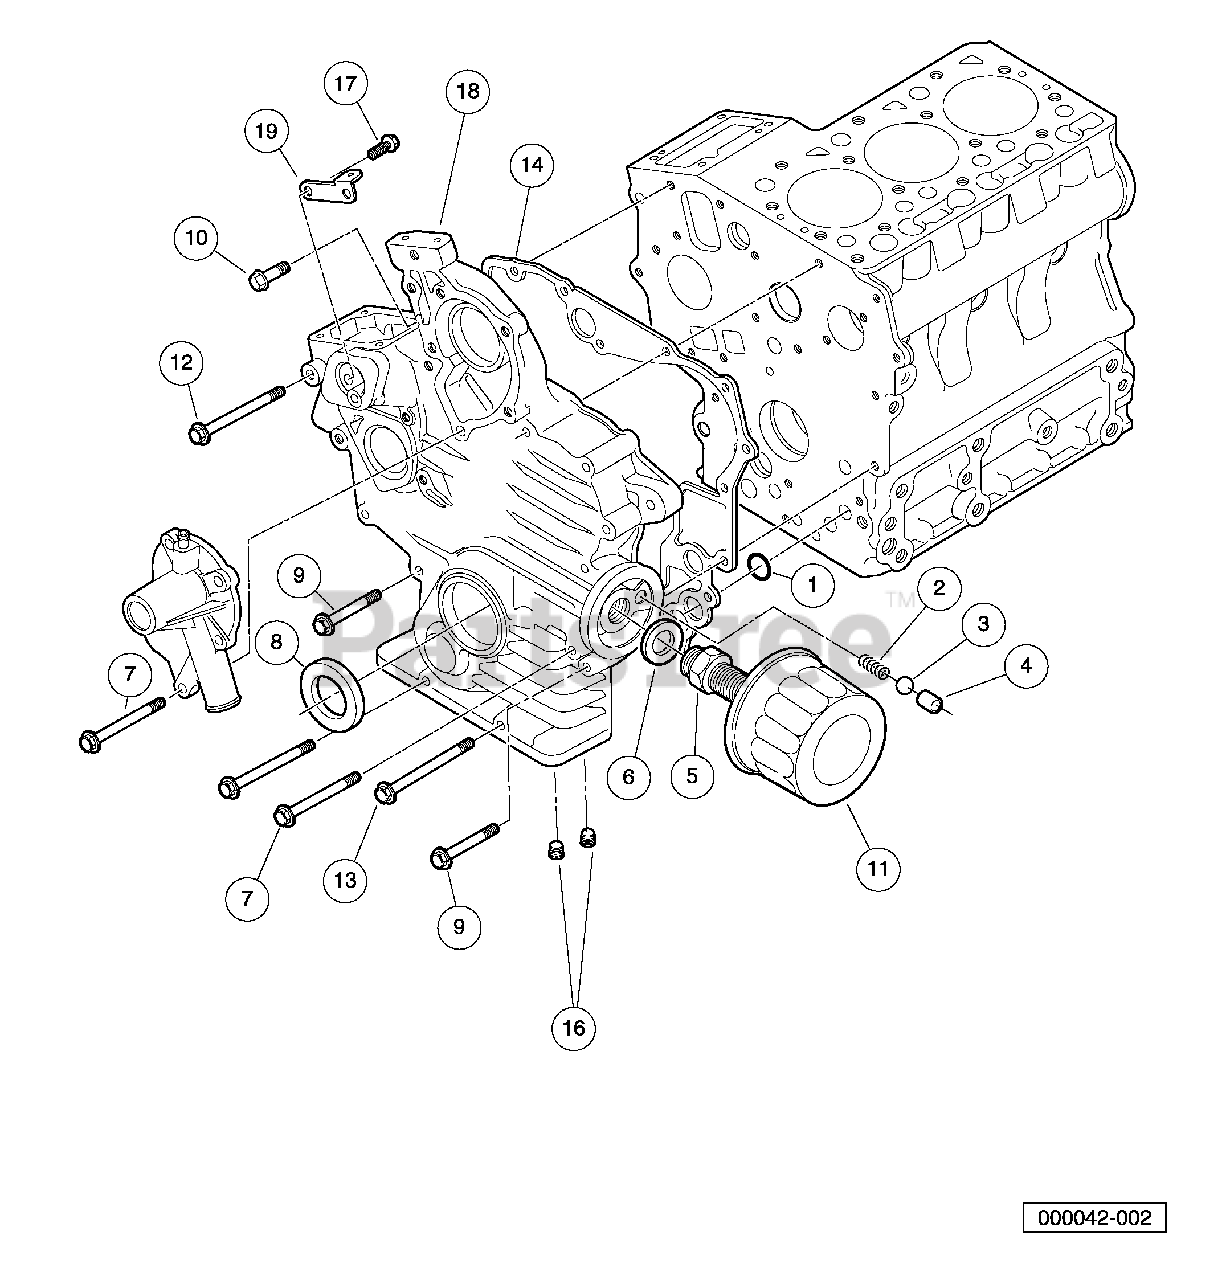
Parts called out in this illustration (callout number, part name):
1	O Ring, 18 X 13
2	Spring, Valve
3	Ball, Valve
4	Seat, Valve
5	Joint, Pipe
6	Washer, Plain, Special
7	Bolt, M6 X 1 X 60
8	Seal, Oil
9	Bolt, D722, Front Case
10	Bolt, D722 Intake Manfld Lower
11	Filter, Engine Oil, D722
12	Bolt, Gearcase, Top
13	Bolt, Gearcase, Lower
14	Gasket, Gearcase, D722
15	Case, Gear
16	Plug, 1/4"
17	Screw, Breather
18	Case, Gear
19	Stay, Spring
